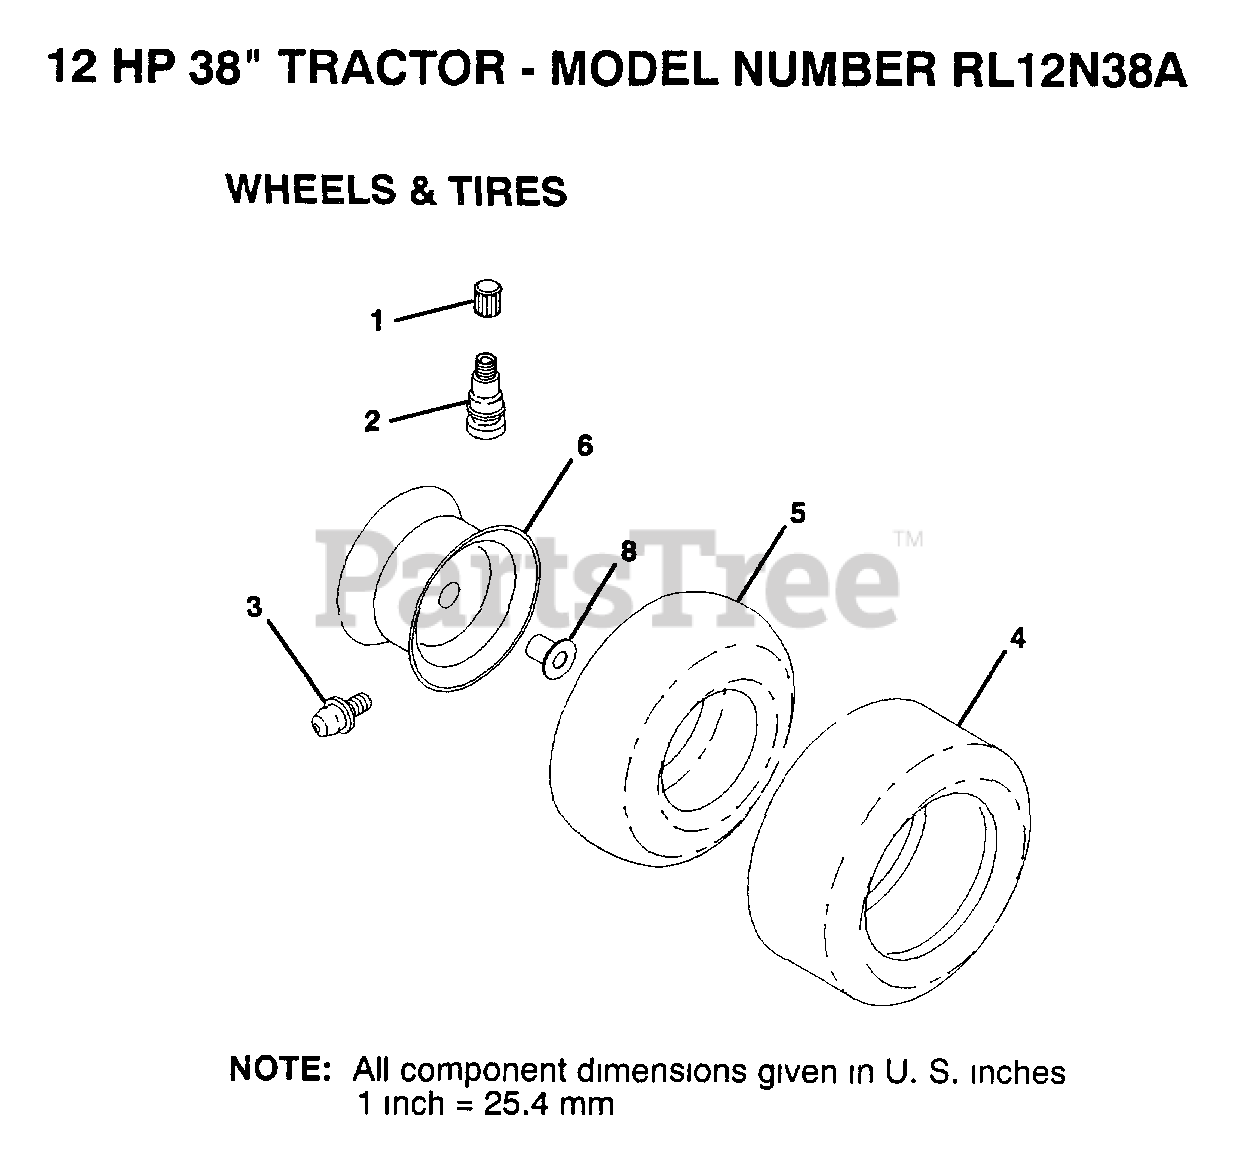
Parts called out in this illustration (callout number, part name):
1	VALVE CAP
2	VALVE STEM LT
3	FITTING LT
4	TIRE.TS2.18X8.5
5	TUBE.18X9.5-8
5	TUBE.5.3/4.5/6
8	"FLANGE, BEARING"
